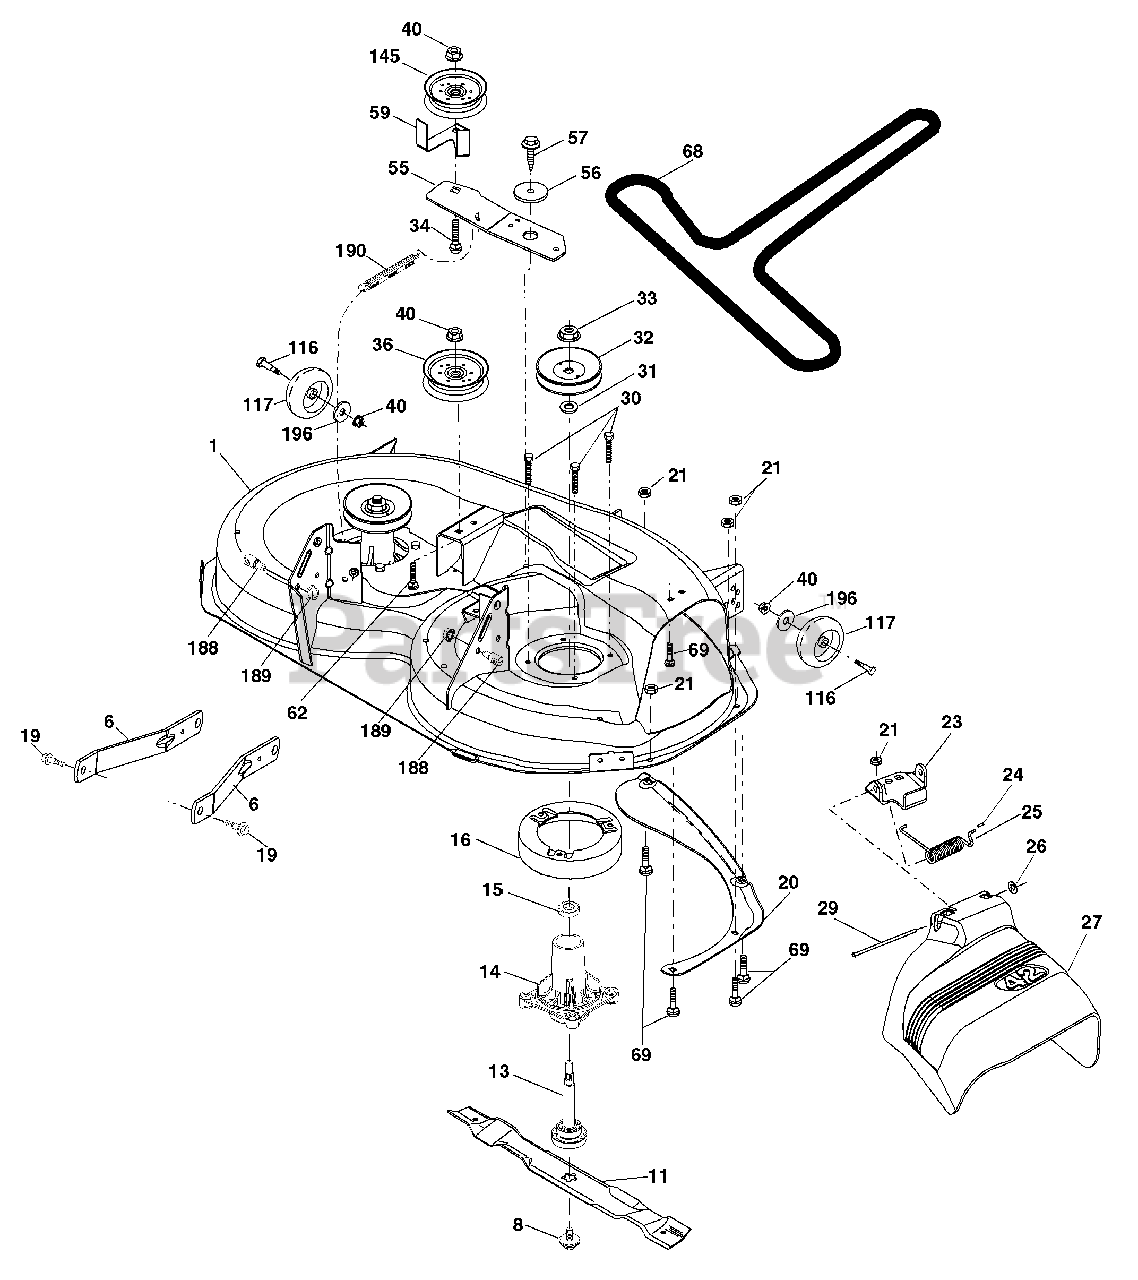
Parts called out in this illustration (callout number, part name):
1	Mower Housing
6	Arm Suspension
8	Bolt/Washer asm 7/16-20 unf
11	Blade, 42" Hi-Lift
11	Blade, 42" Mulching Std
11	Blade, 42" Mulching Premium
13	Shaft Assembly, Mandrel
14	Housing, Mandrel
15	Bearing, Ball, Mandrel
16	Stripper, Mower Deck
19	Bolt, Shoulder
20	Baffl e, Vortex
21	Nut, Crownlock 5/16-18 unc
23	Bracket, Defl ector
24	Cap, Sleeve
25	Spring, Torsion, Defl ector
27	Shield, Defl ector
29	Rod, Hinge
30	Screw Thdrol Rolling Wsh Hd
31	Washer, Spacer
32	Pulley, Mandrel
33	Nut, Toplock, Flanged
34	Bolt Carr Sh. 3/8-16 x 1-1/2 Gr. 5
36	Pulley, Idler, Flat
40	Nut, Lock Flg. 3/8-16 unc
55	Arm, Idler
56	Spacer, Retainer
57	Screw 3/8-16 x 1
59	Guard, Tuv Idler
62	Bolt Rd Hd Sq Nk 3/8-16 unc x 2
69	Bolt
116	Bolt, Shoulder
117	Wheel, Gauge
145	Pulley Idler
188	Stud Fastener
189	Nut Lock Hex Flange
190	Spring Mower Drive
196	Washer 13/32 x 1-1/4 x 12 Ga.
196	Mandrel Assembly
196	Replacement Mower, Complete
